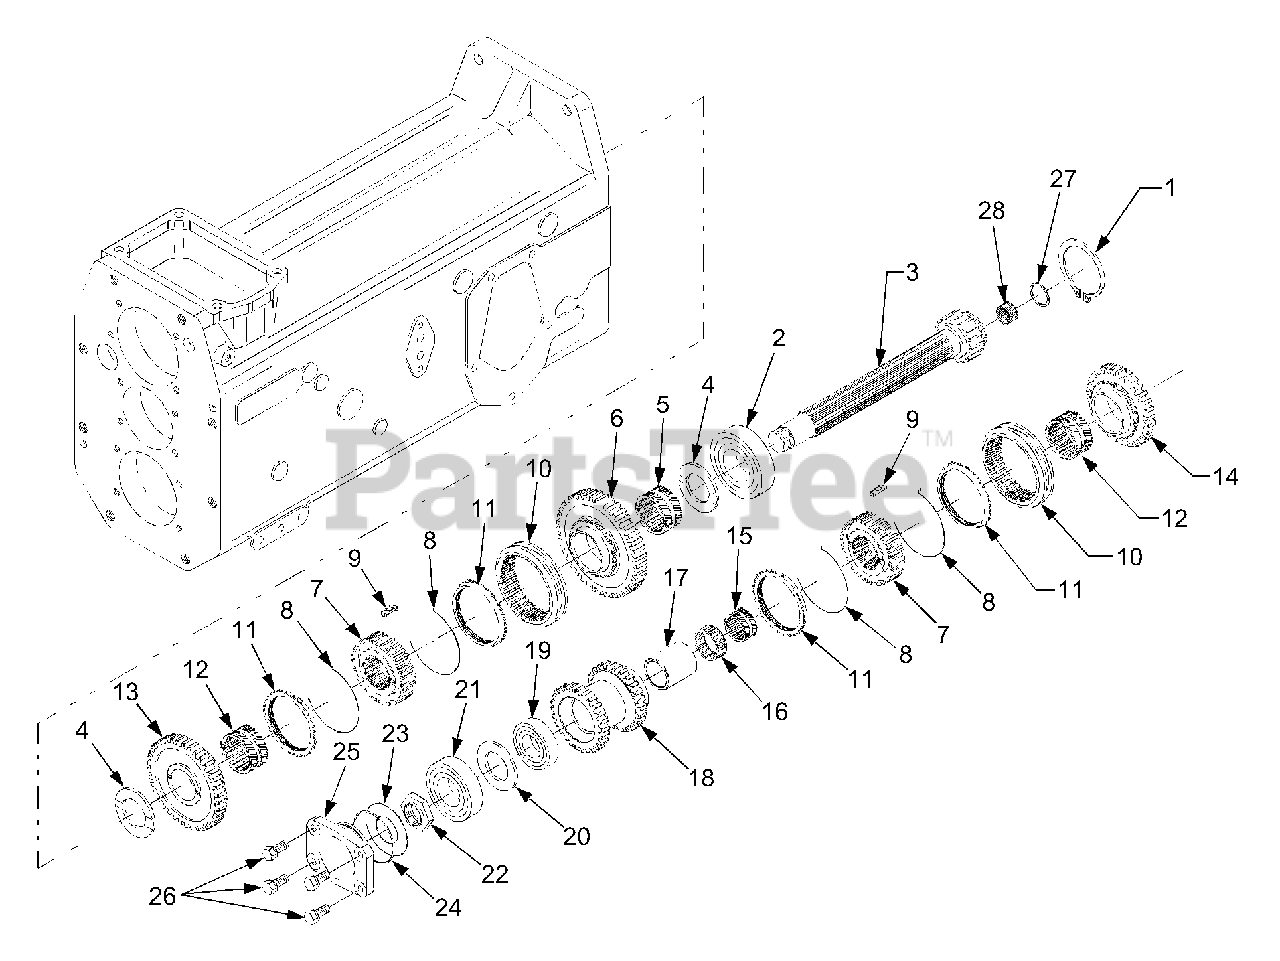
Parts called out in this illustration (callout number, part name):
2	Bearing, Ball
3	Shaft, Gear 17
4	Collar, Thrust
7	Hub, Synchronizer
9	Key, Synchronizer
10	Clutch, Sliding
11	Ring, Synchronizer
16	Bearing, Needle
18	Gear, 26-26
19	Bearing, Ball
21	Bearing, Ball
25	Cover, Bearing
28	Bearing, Needle
